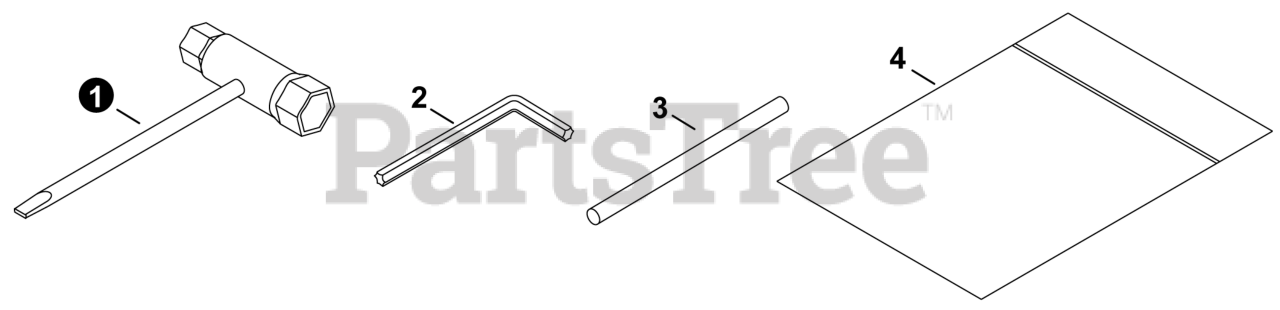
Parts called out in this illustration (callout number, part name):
1	T-WRENCH 17x19 L200
2	WRENCH, ALLEN
3	TOOL, LOCKING 5x120 MM
4	BAG, TOOL
